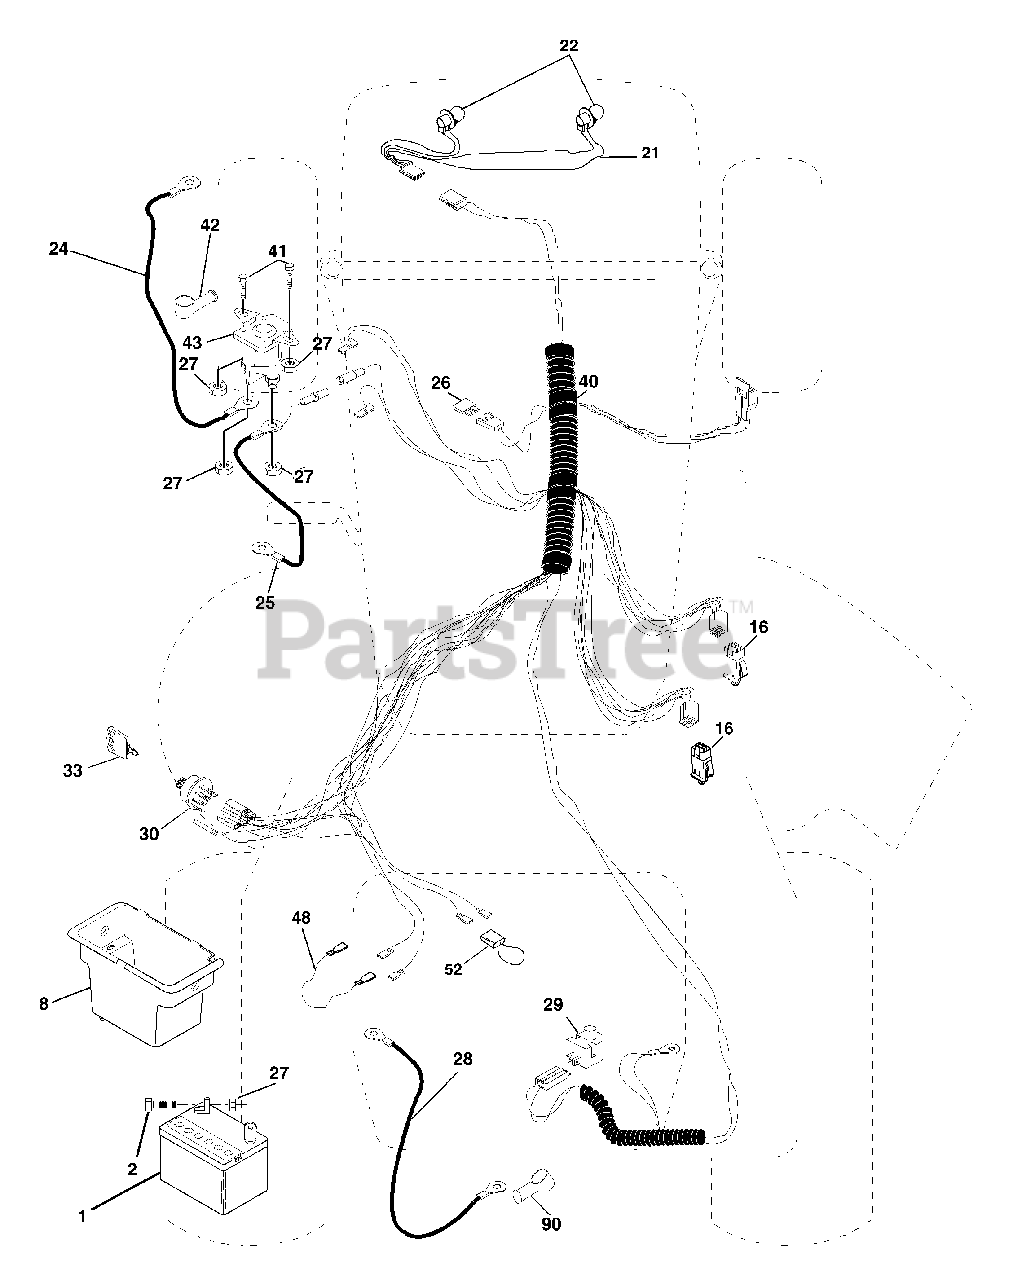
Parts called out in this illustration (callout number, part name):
1	Battery
2	Bolt Hex Hd 1/4-20unc X 3/4
8	Box Battery
16	Switch Interlock
21	Harness Asm Light W/4152j
22	Bulb Light #1156
24	Cable Battery 6 Ga 11" red
25	Cable Battery
26	Fuse 20 AMP
27	Nut Keps Hex 1/4-20 Unc
28	Cable Ground 6 Ga 12" black
29	Switch Plunger Nc Gray
30	Switch Ign
33	Key Ign
40	Harness Ign
41	Bolt Blk Fin Hex 1/4-20
42	Cover Terminal Red
43	Solenoid
48	Adapter Ammeter
52	Protection Wire Loop
90	Cover Terminal Battery
